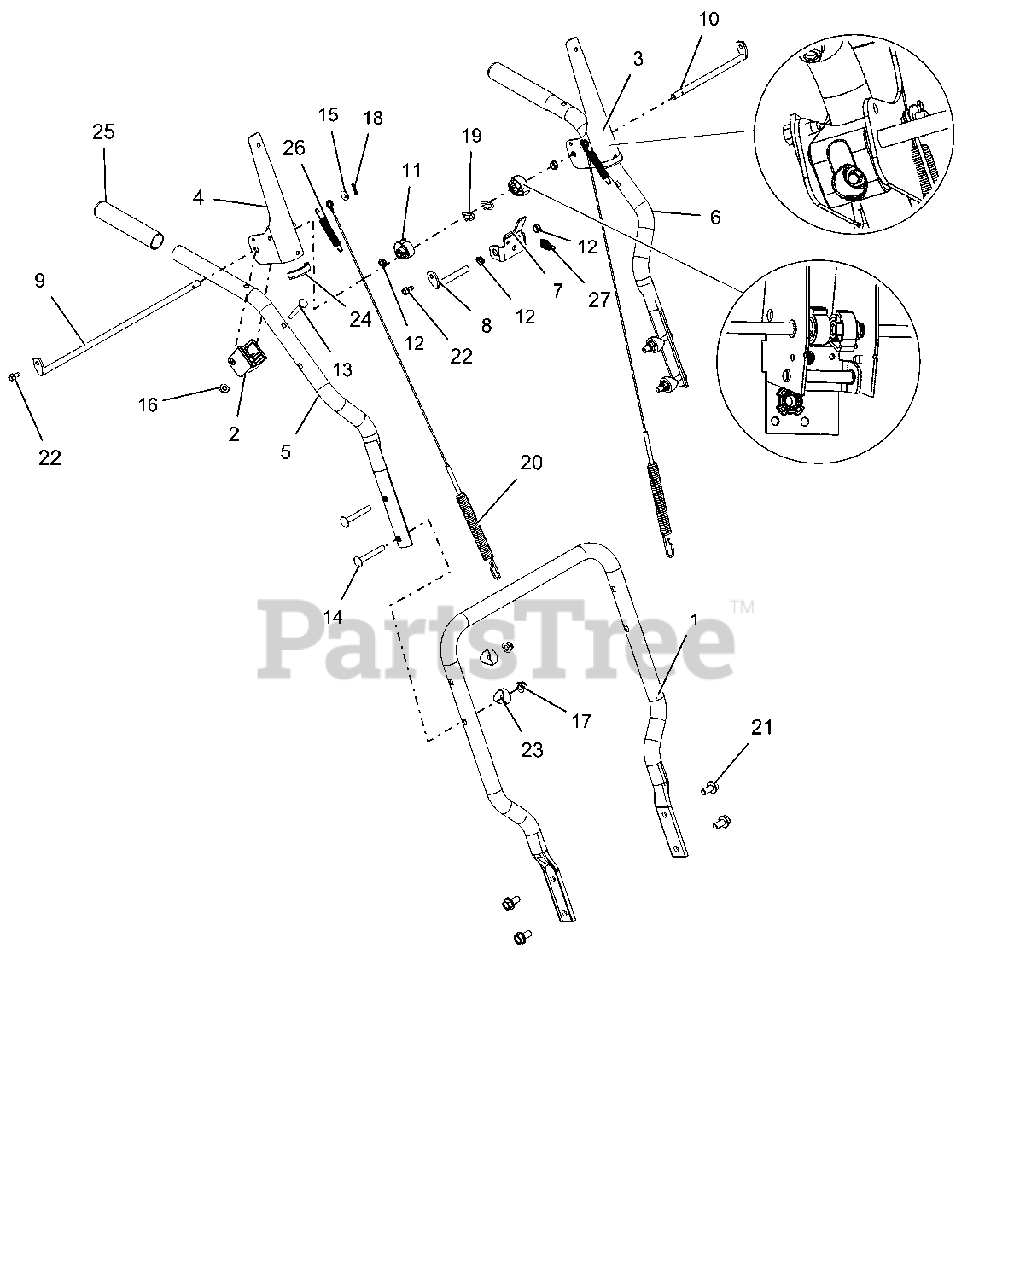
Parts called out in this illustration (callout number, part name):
1	HANDLEBAR, LOWER (COMPACT)
2	BLOCK, CLUTCH PADDLE
3	LEVER, CLUTCH-LH
4	LEVER, CLUTCH-RH
5	HANDLEBAR, UPPER - RH
6	HANDLEBAR, UPPER - LH
7	BRACKET, INTERLOCK ARM
8	ROD, PIVOT - INTERLOCK
9	ROD, PADDLE MOUNT - LONG
10	ROD, PADDLE MOUNT - SHORT
11	CAM, INTERLOCK
12	BUSHING, POLYLINER-.38 SNAPIN
13	BLT-RDHDXLSQNK .25-20X2.0 G5YZ
14	@BLT-RDHDSQNK .31-18X2.25 G5YZ
15	@WSHR-FL-STL.281X.62X.065 YWZC
16	@NUT-LK-TOP-FLG .25-20 YWZC
17	@NUT-LK-NYL-FLG .31-18 YWZC
18	PIN-HAIR INT .06X.18X.77
19	PIN, SPRING CLIP
20	CABLE, AUGER & UPPER TRACTION
21	BLT-SERHFWH .38-16X.75 YWZC
22	SCR-TAP .25-20X.50 HWH TR YWZ
23	SPACER, HANDLEBAR
24	EDGING, CLUTCH PADDLE - 2.00"
25	HANDLE GRIP
26	SPRING, EXTENSION
27	SPRING-EXT .047X.438X1.45
